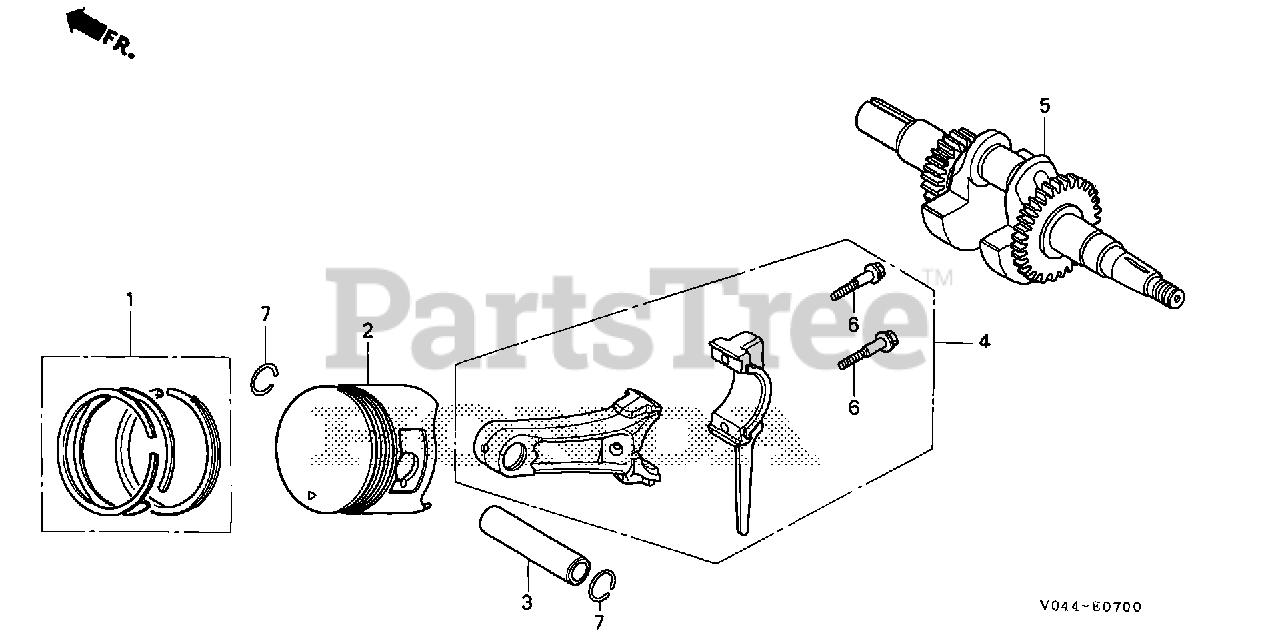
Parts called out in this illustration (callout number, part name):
1	RING SET, PISTON (STD) (TEIKOKU)
1	RING SET, PISTON (STD.) (NIPPON)
1	RING SET, PISTON (STD) (TPR)
1	RING SET, PISTON (0.25) (TEIKOKU)
1	RING SET, PISTON (0.25) (NIPPON)
1	RING SET, PISTON (0.25) (TPR)
1	RING SET, PISTON (0.50) (TEIKOKU)
1	RING SET, PISTON (0.50) (NIPPON)
1	RING SET, PISTON (0.50) (TPR)
1	RING SET, PISTON (0.75) (TEIKOKU)
1	RING SET, PISTON (0.75) (NIPPON)
1	RING SET, PISTON (0.75) (TPR)
2	PISTON (STD)
2	PISTON (0.25)
2	PISTON (0.50)
2	PISTON (0.75)
3	PIN, PISTON
4	ROD ASSY., CONNECTING (STD)
4	ROD ASSY., CONNECTING (TH)
5	CRANKSHAFT
6	BOLT, CONNECTING ROD
7	CLIP, PISTON PIN (18MM)
